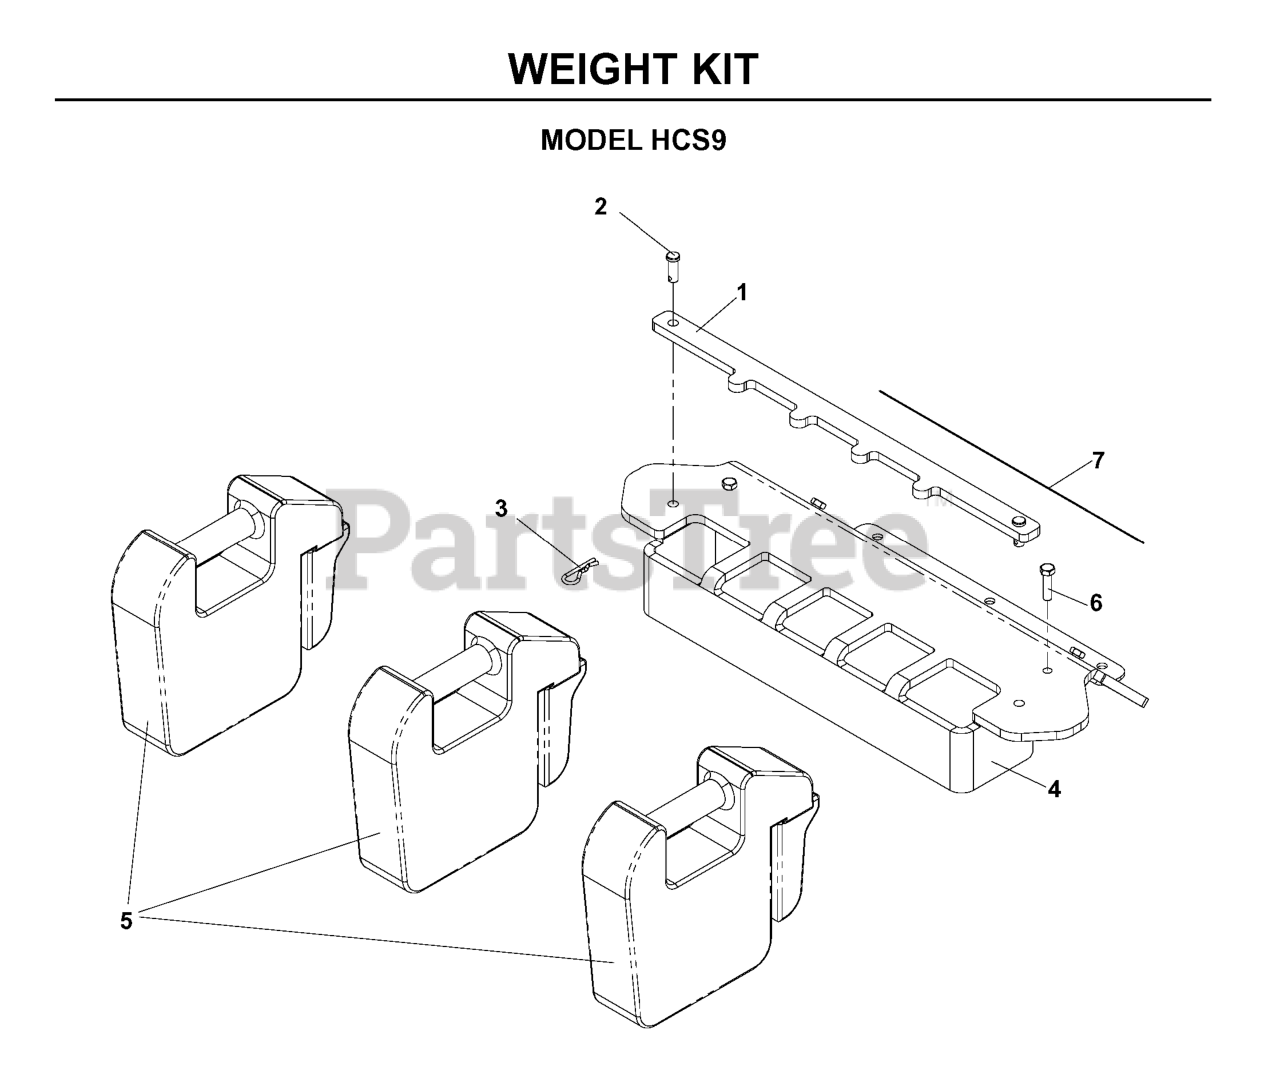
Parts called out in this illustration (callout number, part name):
1	HOLD DOWN, WEIGHT BAR
2	CLEVIS PIN
3	RETAINER SPRING
4	WEIGHT BAR, IZ
5	CAST COUNTERWEIGHT
6	HCS 5/16C X 1 1/4
7	ANTI-SKID PAD
